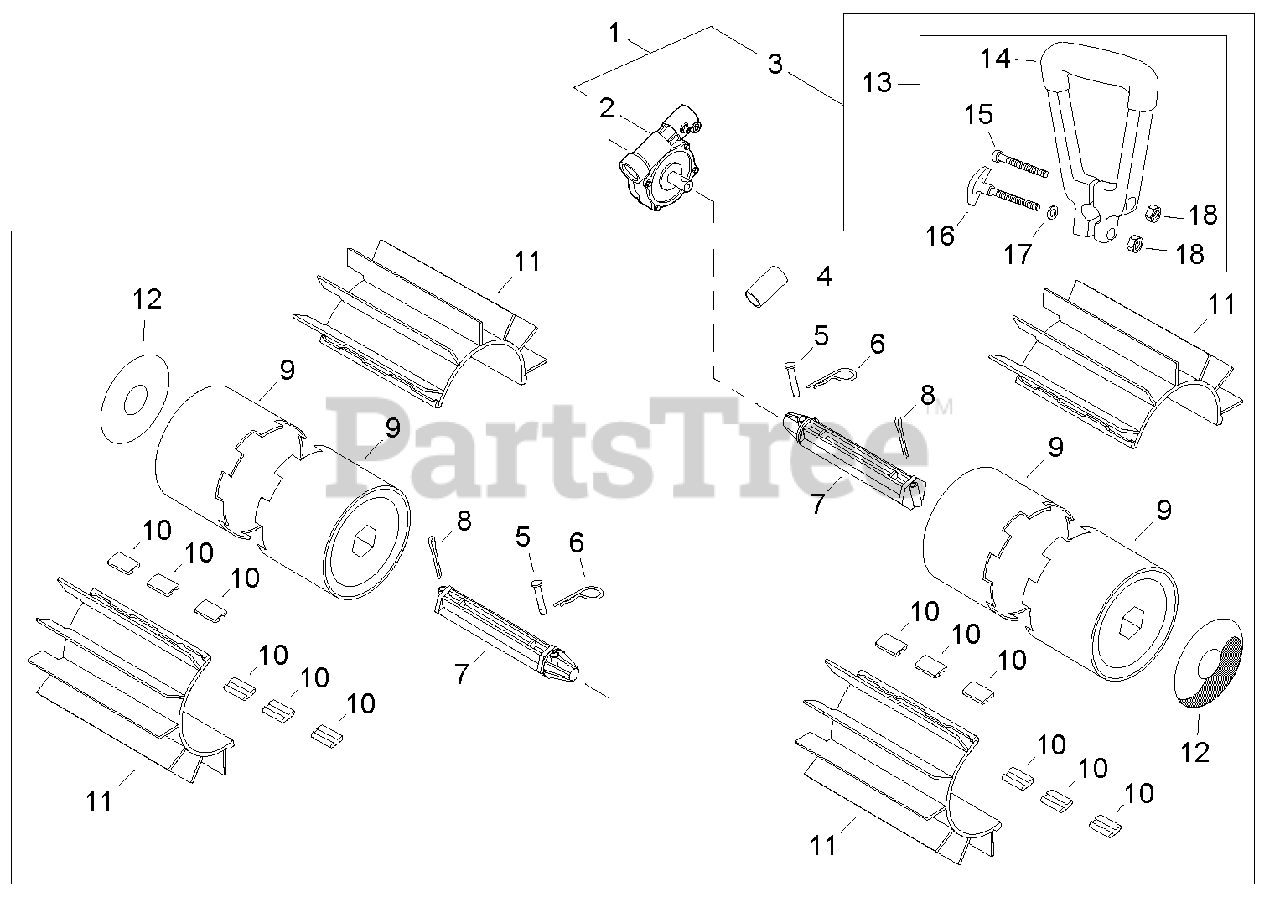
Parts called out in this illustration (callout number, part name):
1	SWEEPER ASSY, 12-FIN RUBBER WITH GEAR CASE
2	GEAR CASE ASSY
3	SWEEPER ASSY, 12-FIN RUBBER
4	PROTECTOR, MAIN PIPE 25 MM
5	PIN, CLEVIS
6	PIN, HITCH
7	AXLE, DRUM
8	PIN, COTTER
9	HUB, DRUM
10	CLIP, BELT
11	BELT, SWEEPER
13	HANDLE ASSY - SUPPORT
14	HANDLE
15	SCREW 6
16	KNOB, SCREW
17	WASHER 6
18	NUT, HEX M6
